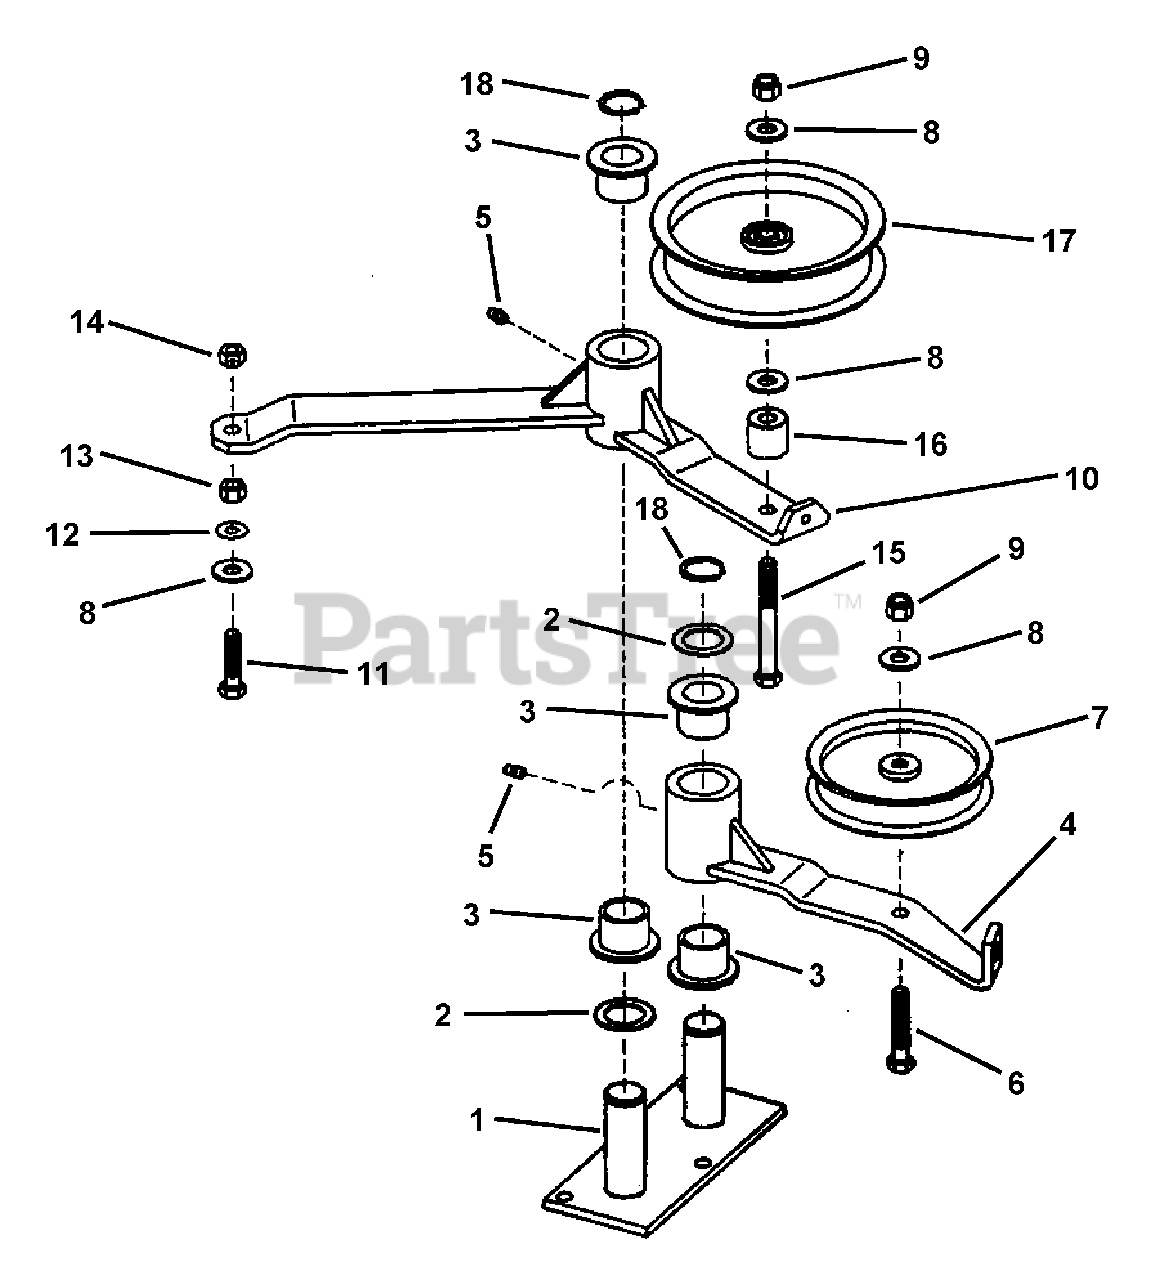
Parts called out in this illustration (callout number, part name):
1	PIVOT, Idler
2	BUSHING
3	BUSHING, Caster
4	IDLER ARM
5	FITTING, Lube
6	BOLT, 3/8-16 X 2, GD5, CZ
7	PULLEY, Idler
8	WASHER, 3/8" USS
9	NUT, 3/8-16 HEX NYLON LOCK
10	IDLER ARM, SPA520
11	SCREW, 3/8-16 x 1-1/2" Hex Head Cap, Grade 5
12	RETAINER, 3/8" Bolt
13	NUT, 3/8-16 Hex, Grade 5
14	NUT, 3/8-16 Hex Center Lock, Grade 5
15	SCREW, 3/8-16 x 3-1/4" Hex Head Cap, Grade 5
16	SPACER, Idler Pulley
17	PULLEY, Idler
18	RING, 1" Retaining
